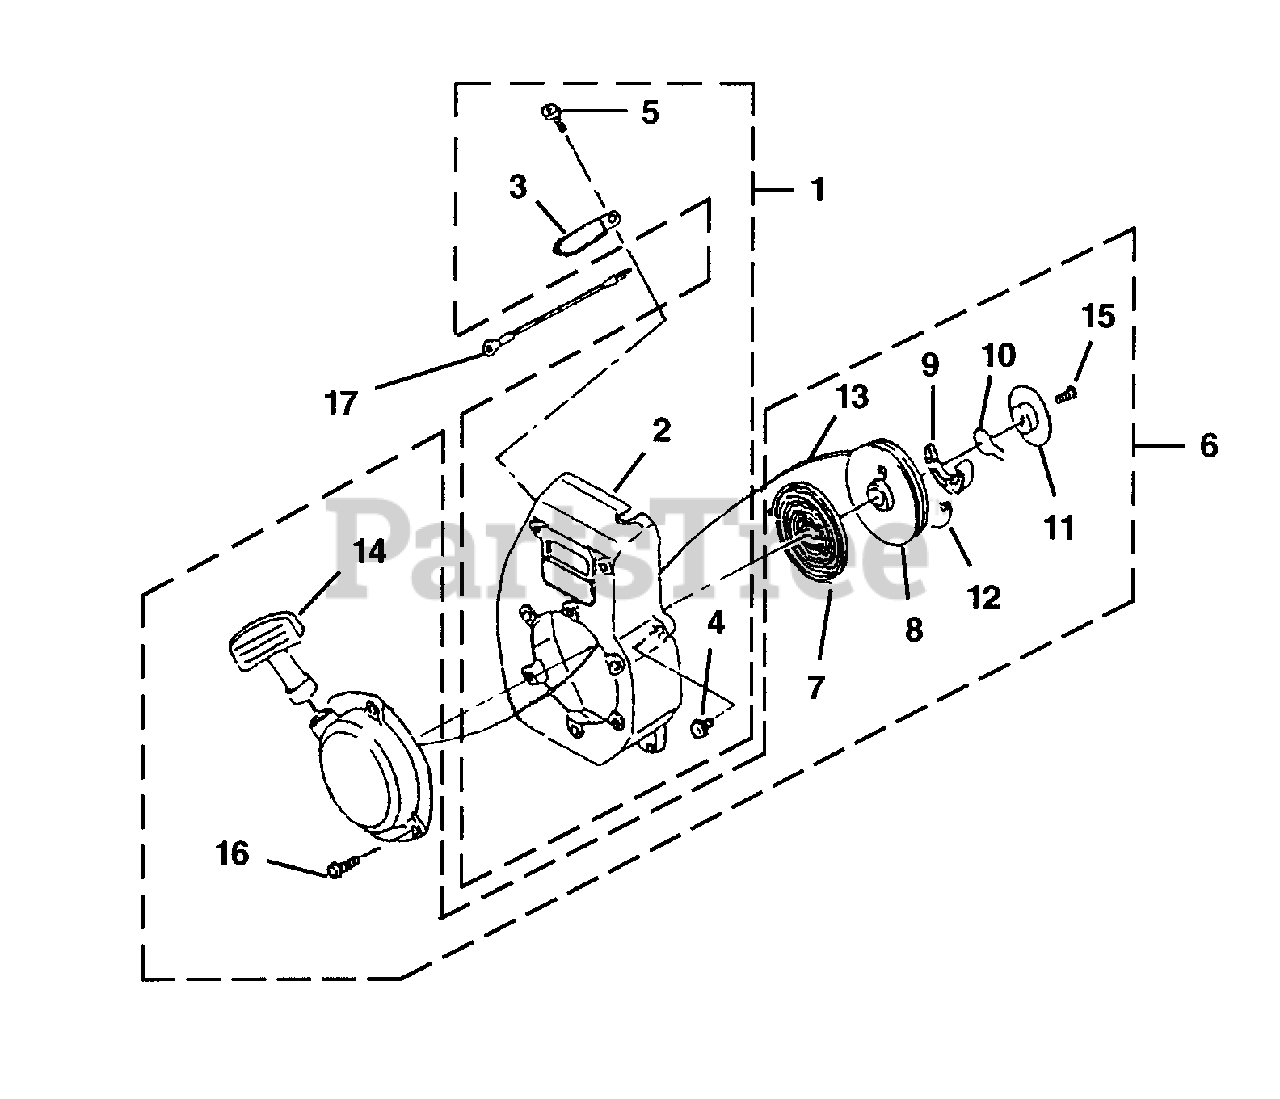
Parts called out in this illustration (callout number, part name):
1	BLOWER HOUSING
2	HOUSING, BLOWER
4	SCREW
5	SCREW
6	STARTER ASSEMBLY
10	SPRING-Friction
11	PLATE-Friction
12	SPRING-Return
13	ROPE - Starter
15	SCREW
16	SCREW
